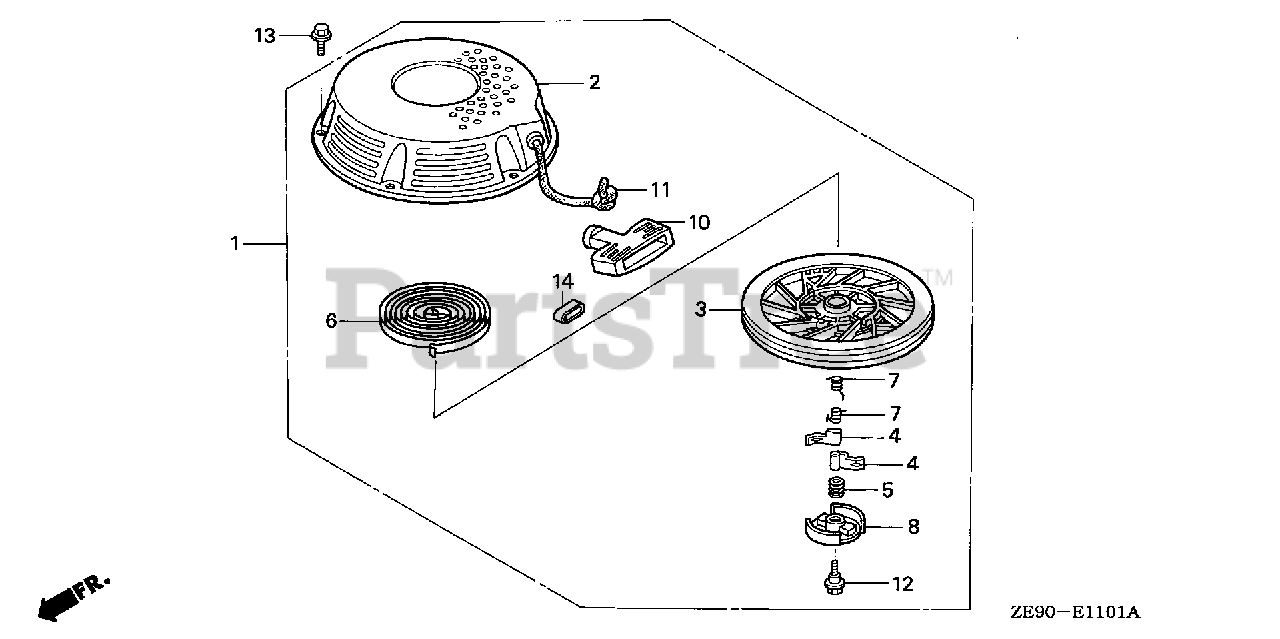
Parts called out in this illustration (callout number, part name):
1	STARTER ASSY., RECOIL *R280* (POWER RED)
2	CASE, RECOIL STARTER *R280* (POWER RED)
3	PULLEY, RECOIL STARTER
4	RATCHET, STARTER
5	SPRING, FRICTION
6	SPRING, STARTER RETURN
7	SPRING, RATCHET
8	RETAINER, SPRING
10	GRIP, STARTER
11	ROPE, RECOIL STARTER
12	SCREW, CENTER
13	BOLT, FLANGE (6X10)
14	REINFORCEMENT, GRIP
